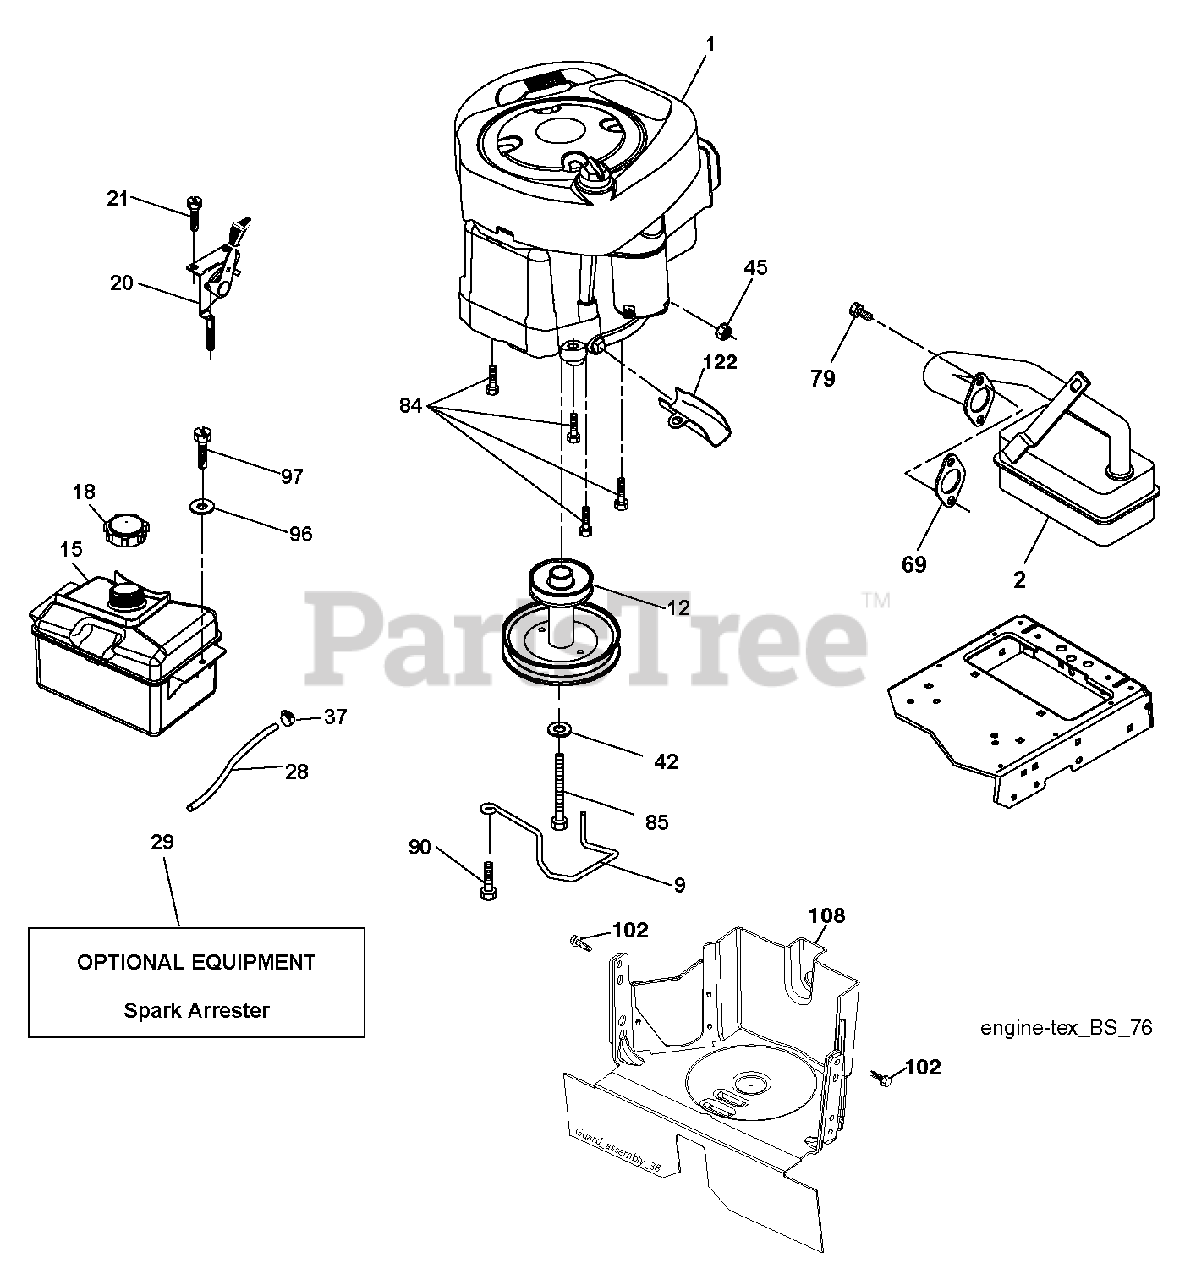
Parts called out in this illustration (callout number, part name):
9	KEEPER.BELT.ENGINE.3.25
12	PULLEY ENGINE
18	CAP ASM.FUEL.2.25"FR.
20	CONTROL.TH/CK.C.
21	SCREW.#10 X 0.750.BOS THREAD
28	LINE.FUEL.20
29	ARRESTER SPARK (OPTIONAL)
37	HOSE CLAMP
42	LOCKWASHER
45	NUT
69	REPL BY 532 27 22-93
79	SCREW.SOCKET HD.5/16-1
84	SCREW.3/8-16
85	BOLT HEX 7/16-20X4-1/4"
90	SCREW 3/8-16X1
97	SCREW HEXWSHR 1/4-20X3/4
102	SCREW
122	EXTENSION DRAIN OIL
